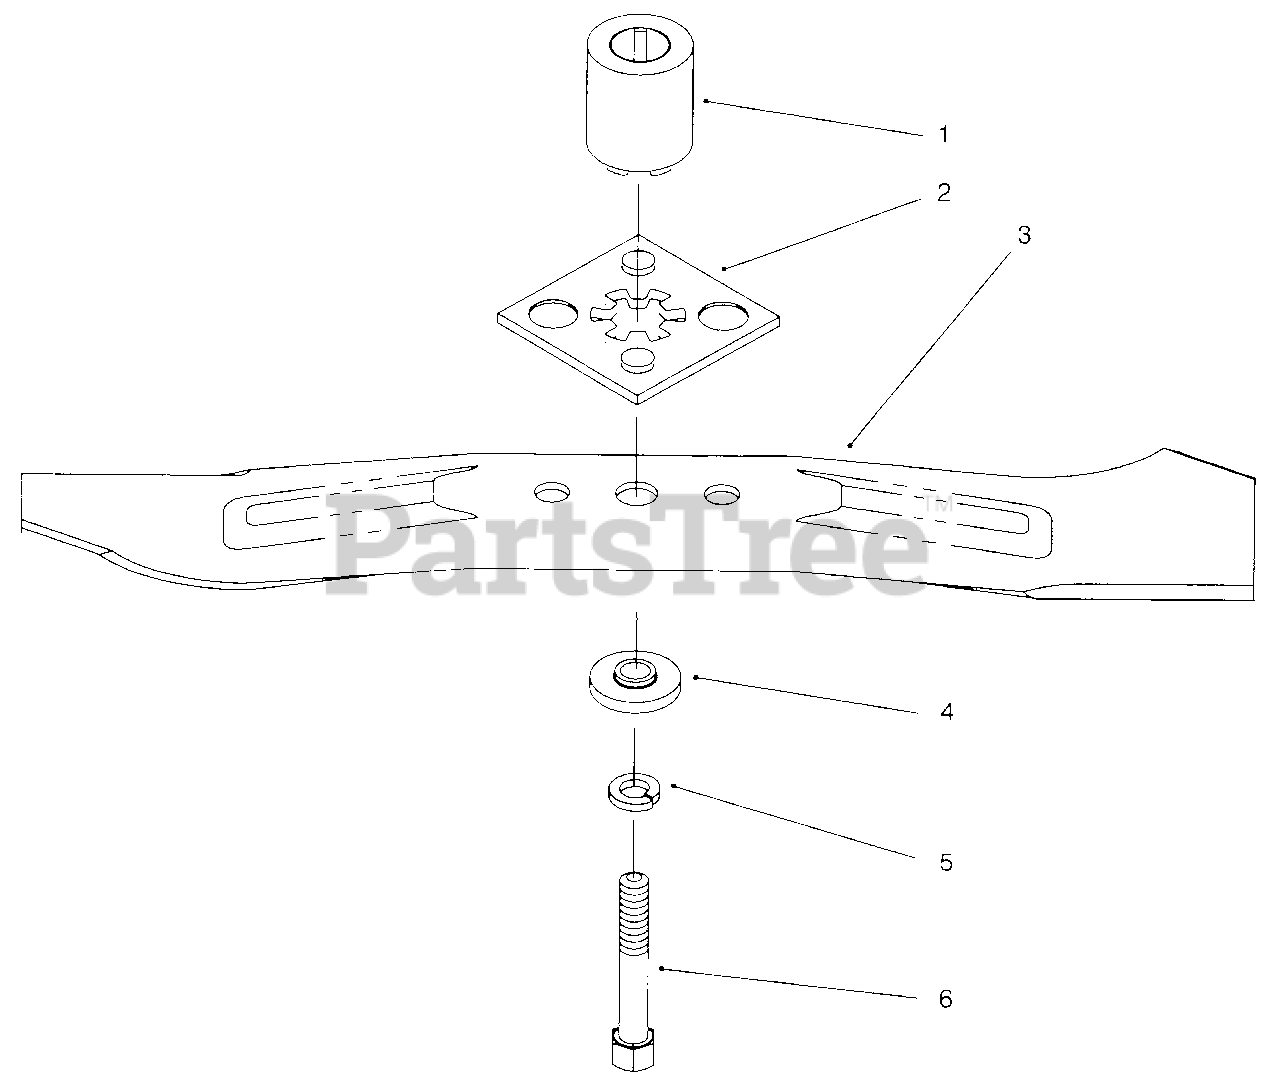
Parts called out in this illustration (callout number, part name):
1	Hub-Blade Driver
2	Plate-Blade Driver
3	Blade-48cm
4	Spacer-Blade
5	Washer-Lock
6	Bolt-Blade
